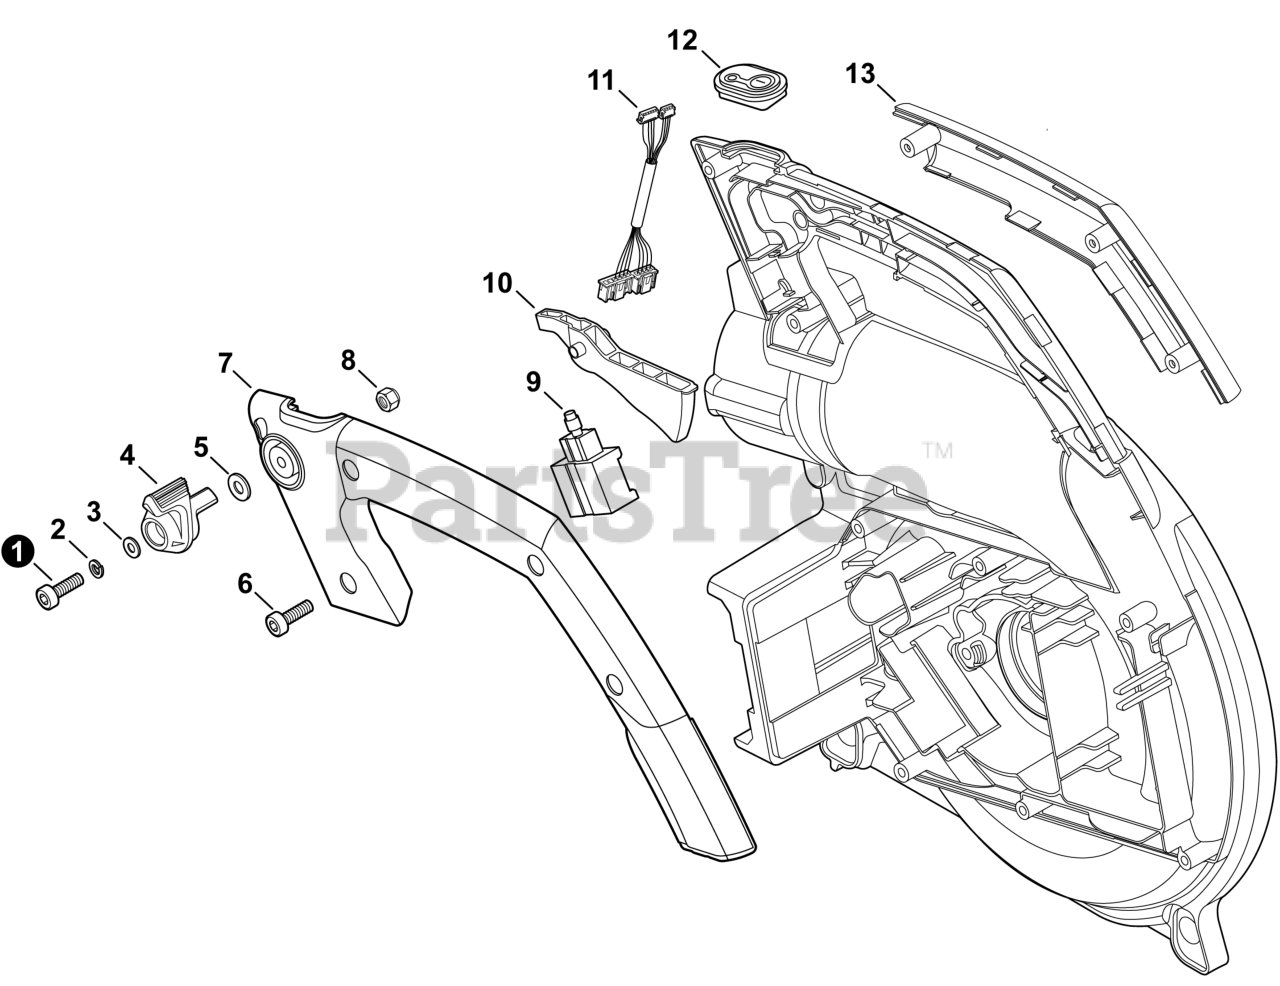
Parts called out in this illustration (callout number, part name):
1	BOLT, TORX 5x25
2	WASHER, SPRING 5
3	WASHER 5.3x10x1
4	LEVER, CRUISE CONTROL
5	WASHER 5.5x12x0.8
6	BOLT, TORX 4x16
7	COVER, HANDLE
8	NUT, LOCK M5
9	SWITCH, SPEED CONTROL
10	TRIGGER
11	LEAD, ON-OFF
12	SWITCH, ON-OFF
13	GRIP, HANDLE
